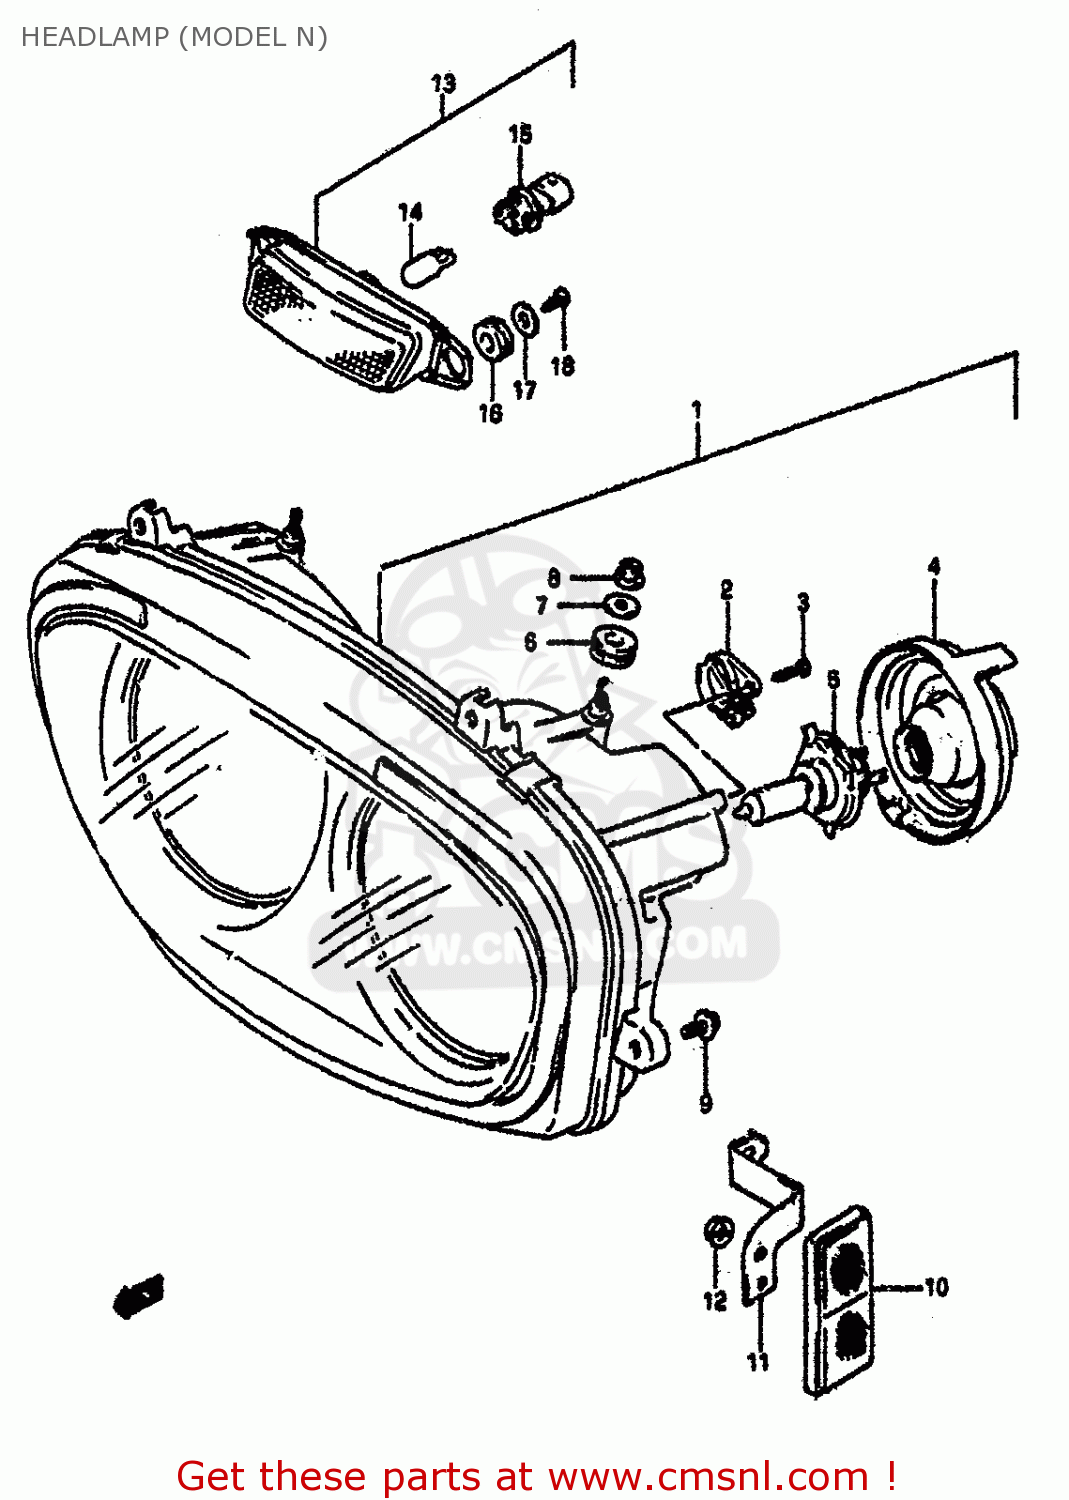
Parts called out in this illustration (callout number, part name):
1	HEADLAMP ASSY
2	GEAR UNIT ASSY,LWR
3	SCREW
4	COVER,SOCKET
5	BULB(12V60/55W,H4)
6	GROMMET
7	WASHER
8	NUT 6MM
9	SCREW
10	REFLECTOR,REFLEX FR
11	BRACKET,FR SIDE RR,R
12	NUT
13	LAMP ASSY,FR POSITION
14	BULB(12V5W)
15	SOCKET ASSY
16	CUSHION
17	WASHER (4X16X1.2)
18	SCREW
